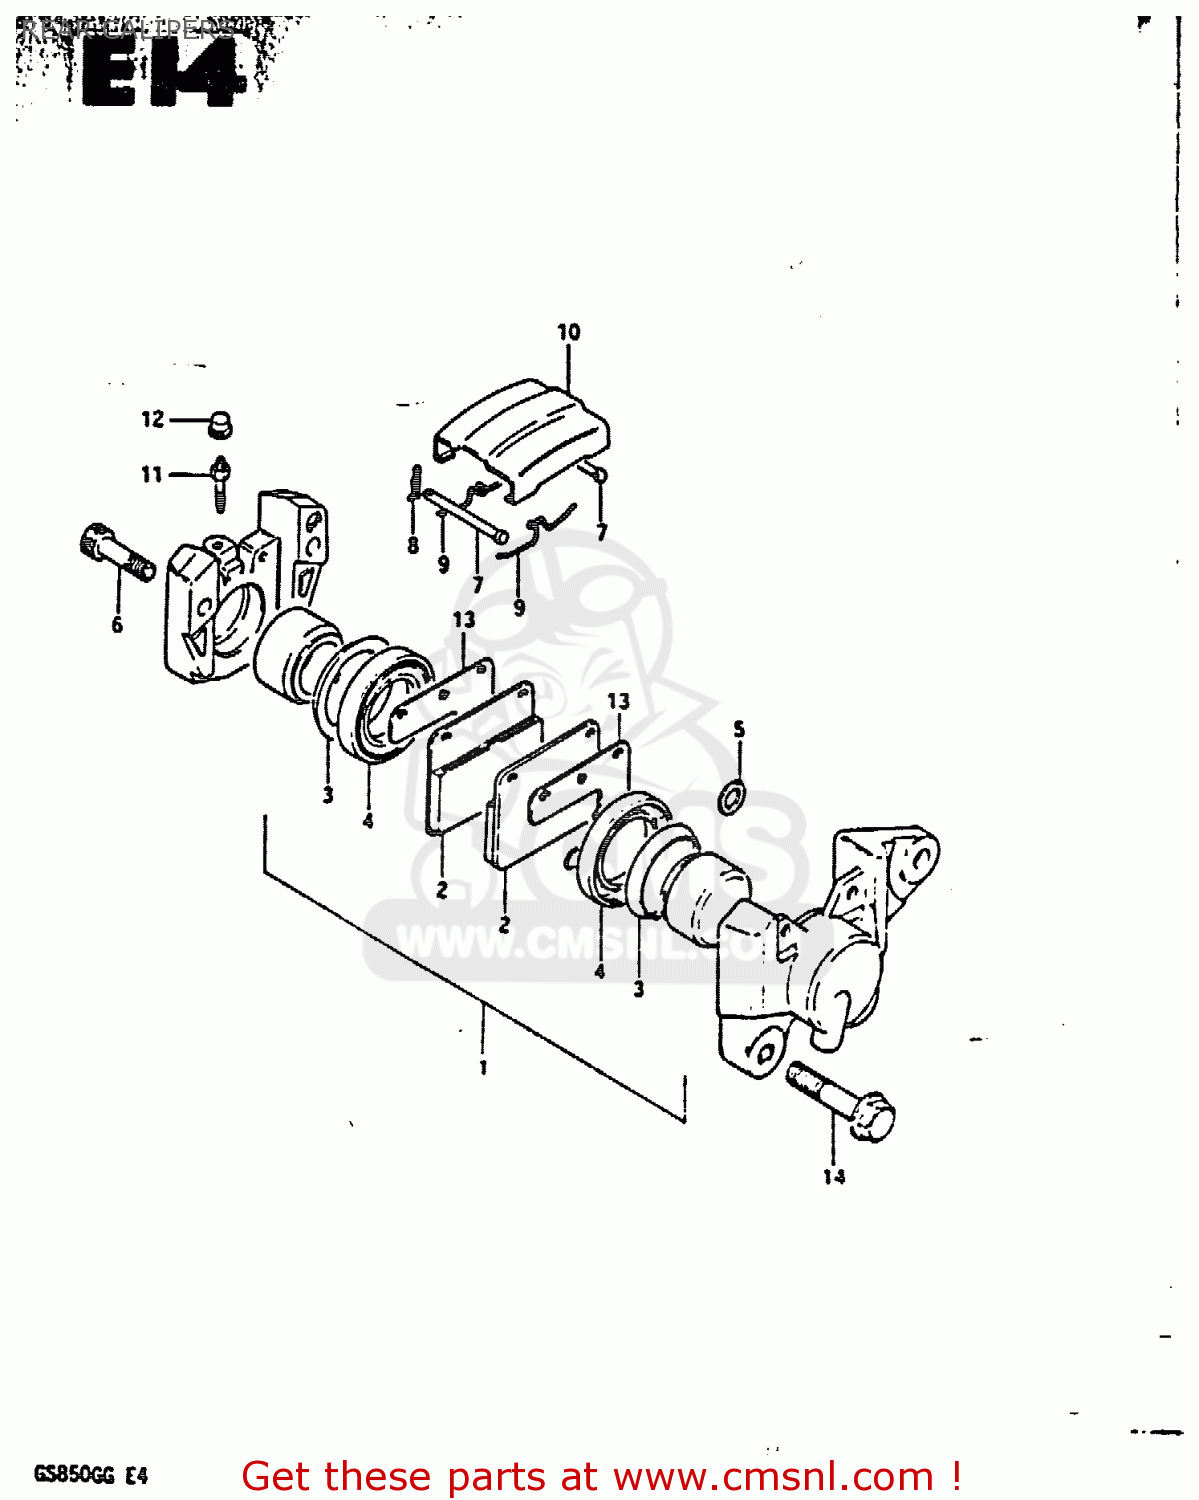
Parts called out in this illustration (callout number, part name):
1	PISTON SET
2	PAD,BRAKE (MCA)
3	SEAL,PISTON
4	BOOT,PISTON
5	SEAL,JOINT
6	BOLT,CALIPER HOUSING
7	PIN,PAD
8	CLIP,PAD PIN
9	SPRING
10	COVER,DUST
11	BLEEDER
12	CAP,BREATHER
13	SHIM,RR CALIPER
14	BOLT
